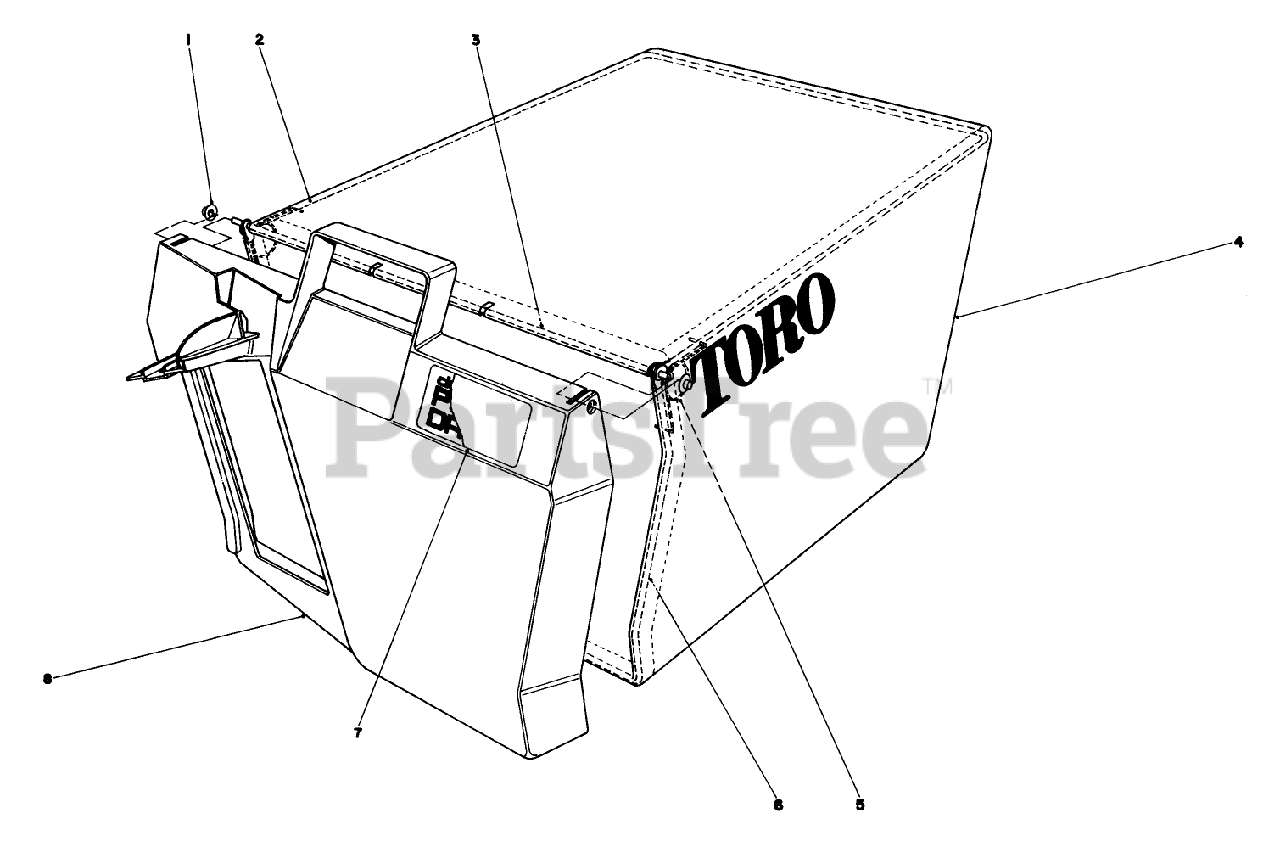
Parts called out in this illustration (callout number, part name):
1	NUT-PUSH
3	HINGE-DOOR, BAG
5	SPRING
